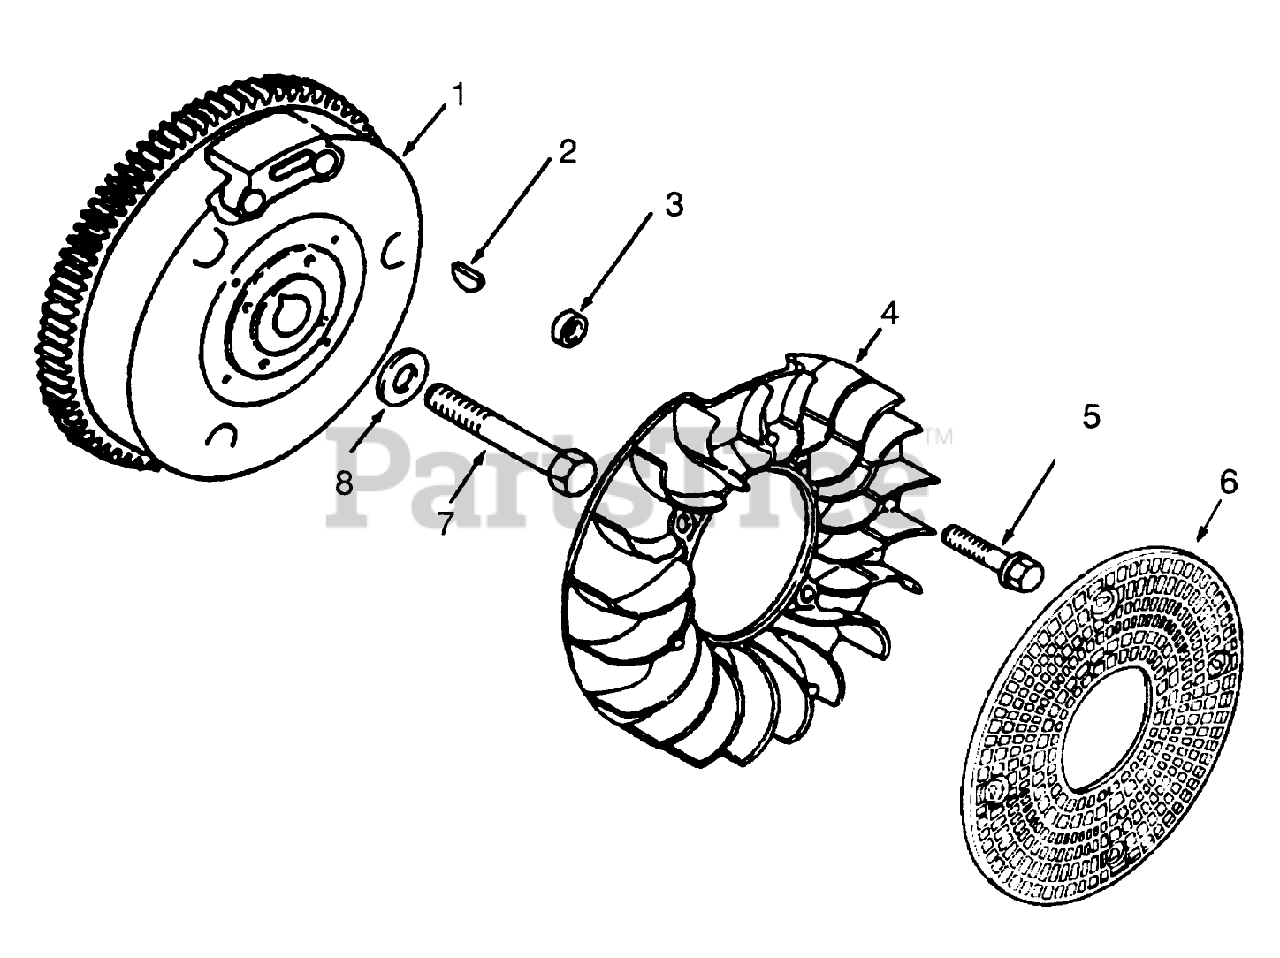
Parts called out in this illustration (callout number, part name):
1	KOHLER 47-025-53
2	KOHLER X-46-3
3	KOHLER 41-100-01
4	KOHLER 25-157-01
5	KOHLER 25-086-21
6	KOHLER 25-162-01
7	KOHLER 25-086-24
8	KOHLER 52-468-15
